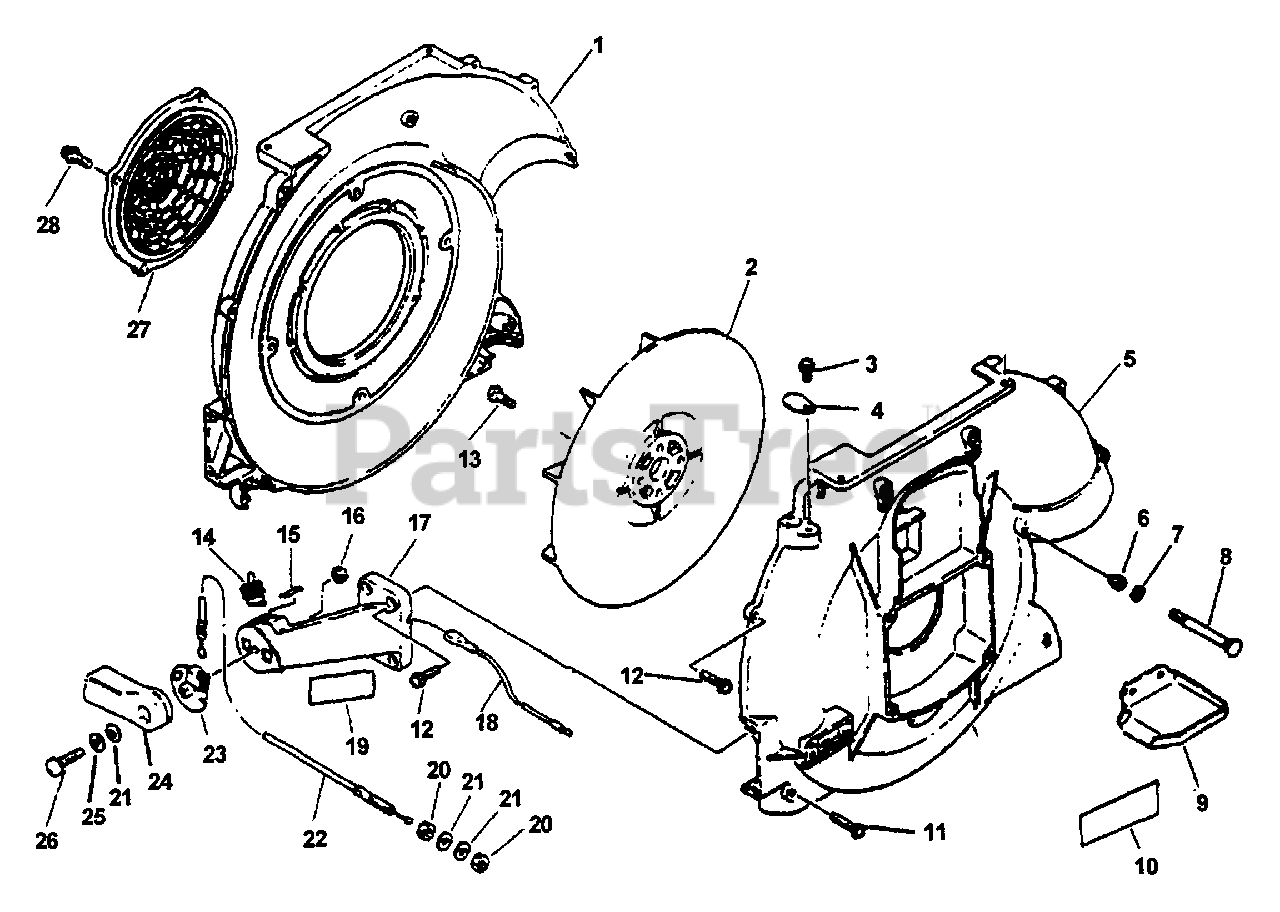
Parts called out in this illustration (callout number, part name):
1	COVER, FAN - INNER -- ORANGE
3	SCREW 5×10
5	COVER, FAN - OUTER
6	NUT - 5 -- CAP
7	WASHER, FLAT 5.5×10×0.8
9	BRACKET, MUFFLER COVER
10	LABEL - NOISE
11	SCREW 5×25
12	SCREW 5×20
14	IGNITION SWITCH ASSY
15	LABEL, ON-OFF
16	NUT, HEX M6
17	MOUNT, THROTTLE LEVER
19	LABEL - CAUTION
22	CABLE, THROTTLE
24	CONTROL, THROTTLE
25	WASHER, SPRING 6
26	SCREW 6×25
27	SHIELD, DEBRIS
